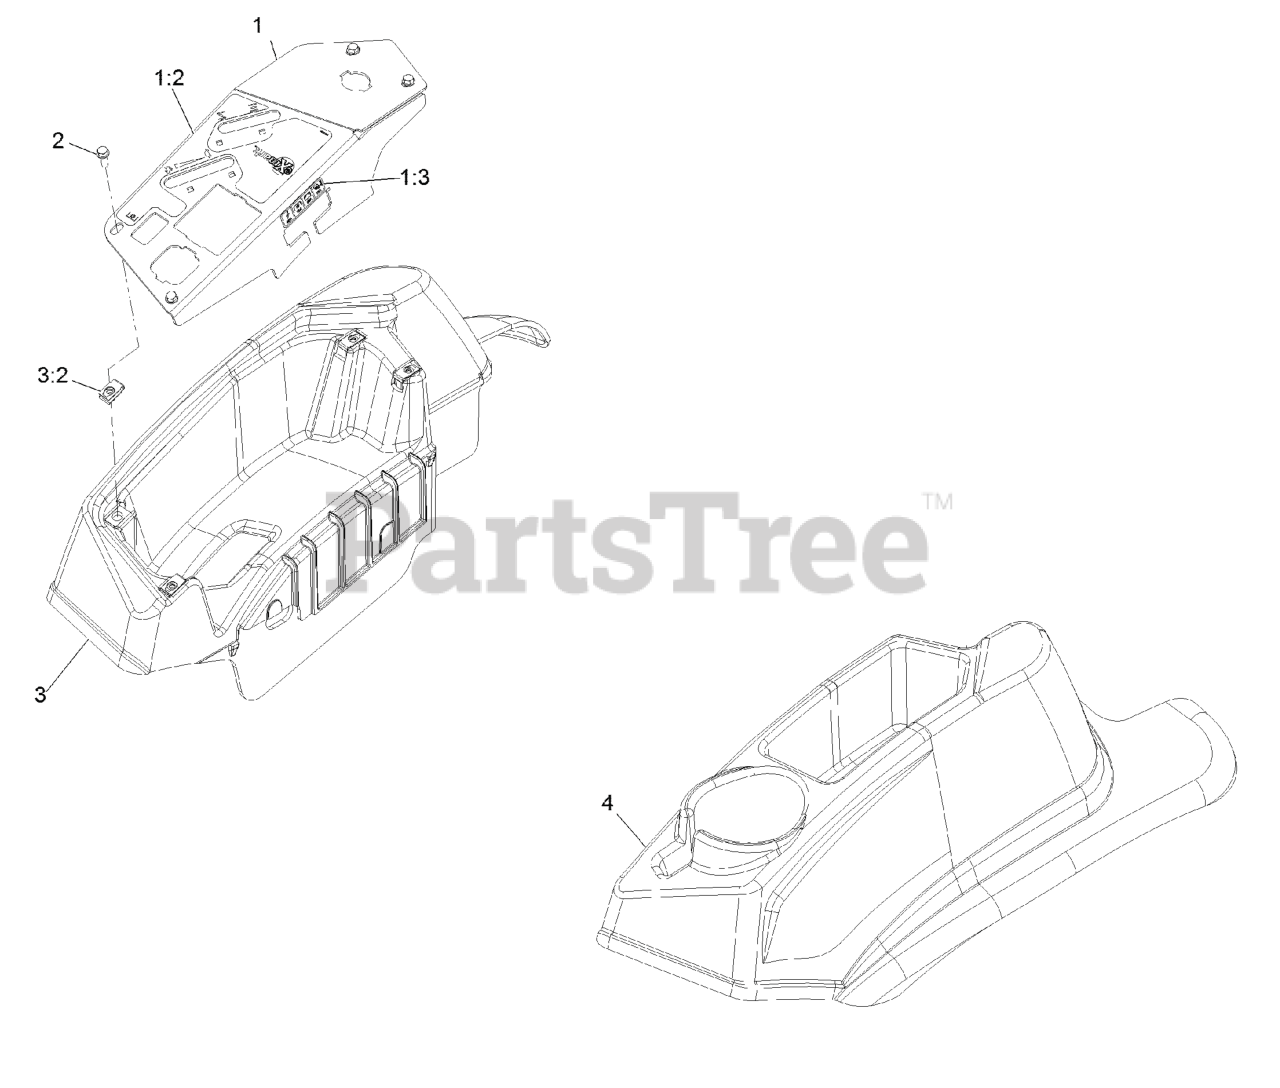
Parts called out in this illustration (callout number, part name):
1	CONSOLE,PANEL W/DECAL
1:2	DECAL-CONTROL PANEL NON-E
1:3	DECAL-FUSES
2	ASM, CHOKE CABLE
3	ASM,THROTTLE CABLE
4	BOLT-CARR
5	NUT-LOCK, NI
6	SCREW-HWH
7	CONSOLE,RH AS ASM
8	CONSOLE, LH AS
9	CLAMP-HOSE
10	PLUG-PLASTIC
